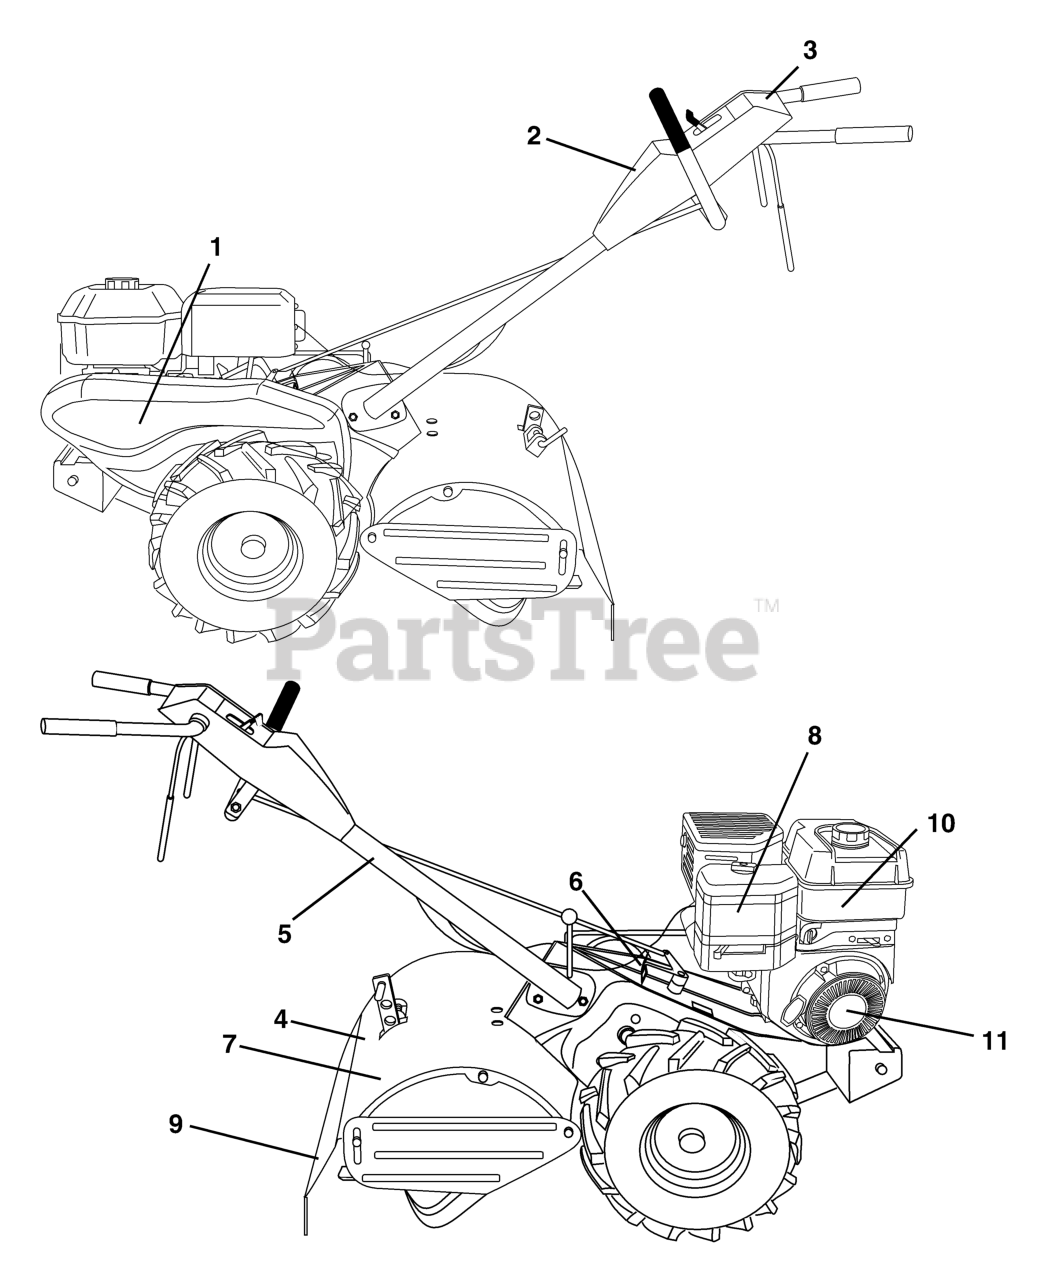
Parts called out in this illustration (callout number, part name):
2	DECAL, 650CRT
3	DECAL.CNTRL.PNL
4	DECAL, TINESHEILD
5	DECAL TI (2 2)
6	DECAL.SHIFT.INDICATOR.TILLER
7	DECAL -CAUTION
9	DECAL TI
10	DECAL.ENG.INTK.B&S.206CC
11	DECAL.REWIND
